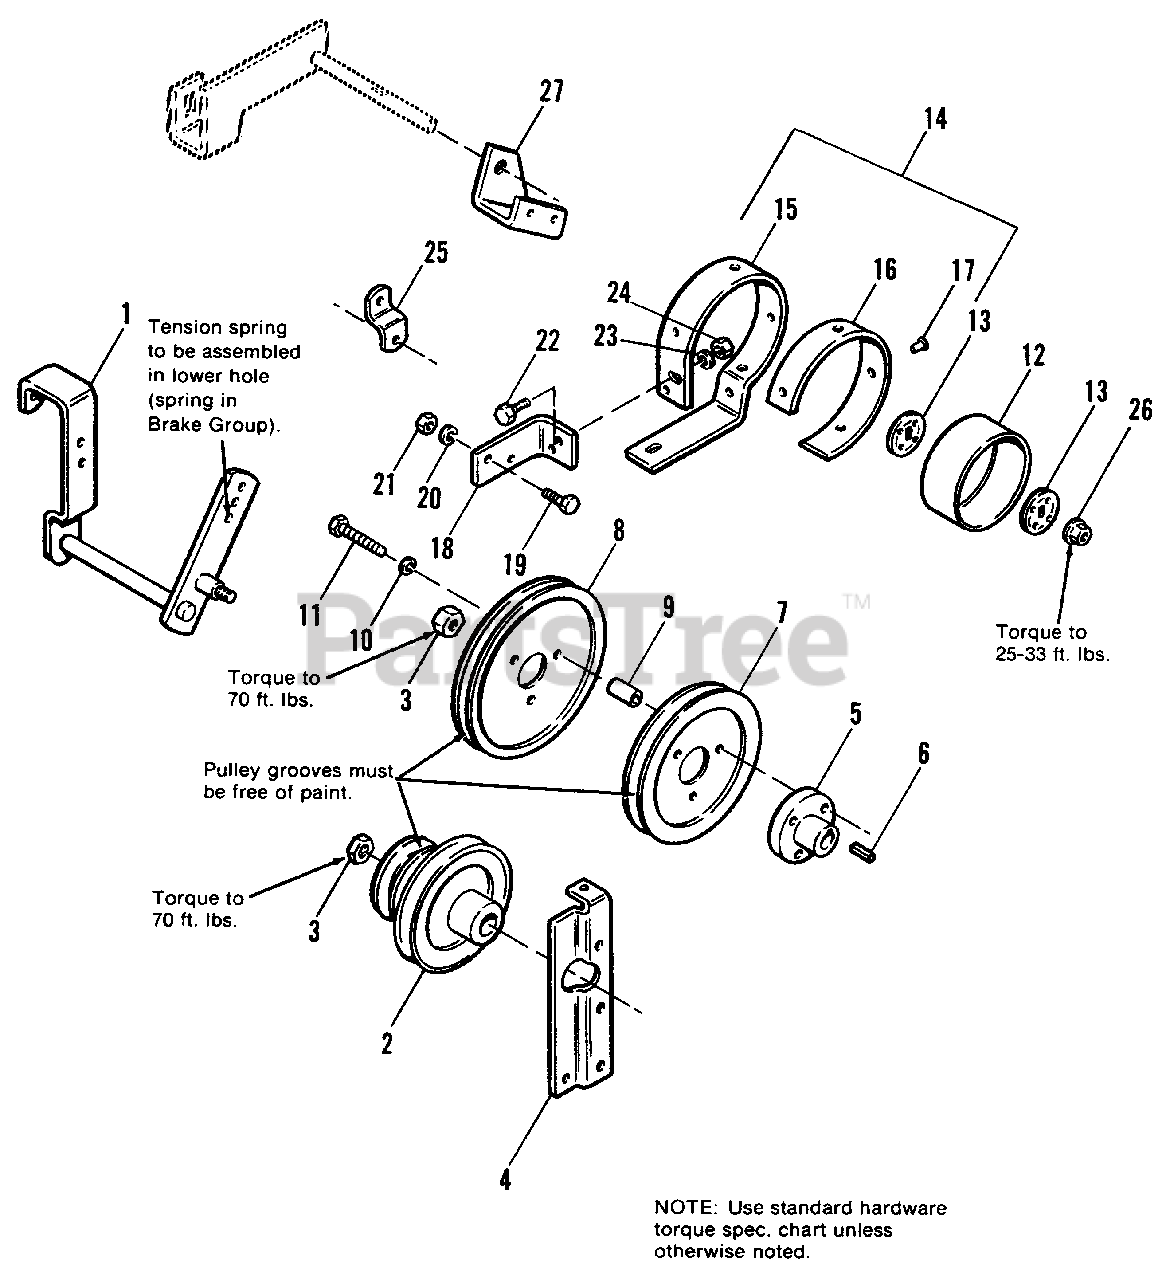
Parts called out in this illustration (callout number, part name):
1	PIVOT LEVER ASSY.
2	FRONT PULLEY ASSY.
3	LOCKNUT, Jam, 3/4-16
4	SUPPORT, Belt Retainer
5	HUB, Pulley
6	KEY, Woodruff #9
10	LOCKWASHER, 5/16
11	CAPSCREW, Hex Hd., 5/16-18 x 2
12	DRUM, Brake
13	WASHER, Special
14	BRAKE BAND ASSY.
16	LINING, Brake
17	RIVET, Tubular
18	BRACKET, Brake Band
19	CAPSCREW, Hex Hd., 3/8-16 x 1-1/4
20	LOCKWASHER, 3/8
21	NUT, Hex, Full, 3/8-16
22	CAPSCREW, Hex Hd., 1/4-20 x 3/4
23	LOCKWASHER, 1/4
24	NUT, Hex, Full, 1/4-20
25	CLIP, Spring
26	LOCKNUT, Hex, Flange, Whiz, 7/16-14
27	BEARING, Idler Pivot
